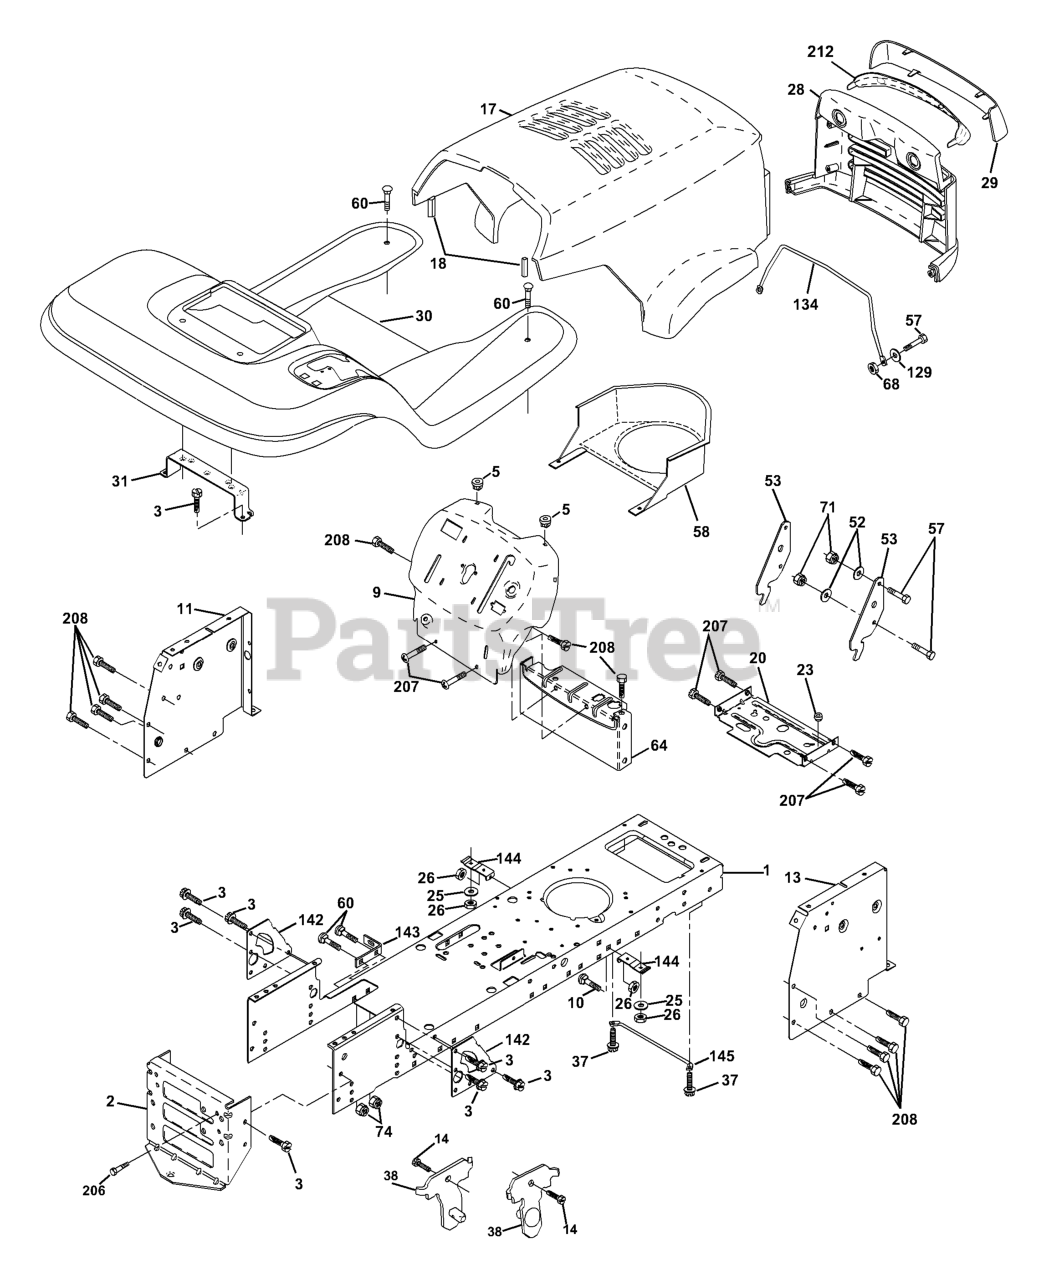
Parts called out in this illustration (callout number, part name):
1	CHASSIS STAMPING
2	DRAWBAR, 12GA
3	SCREW 3/8-16X3/4
5	BUMPER.RUBBER.HOOD
10	BOLT D
11	PANEL DASH LH
13	DASH PANEL ASM.
14	SCREW LT
17	HOOD
18	BUMPER HOOD T
20	PLATE MTG
23	BUSHING.SNAP.NYL.BLK.
25	WASHER
26	NUT
28	GRILL
29	LENS
30	FENDER, FOOTREST
31	BRACKET.SUPPORT.FENDER
37	Screw Thdrol 5/16-18 x 1/2 TYT
38	BRACKET.ASM.PIVOT.MOWER.REAR
52	WASHER
53	BRACKET PNT PICK OFF LT/PL
57	BOLT
58	AIR DUCT P/L/LT
60	Bolt Rdhd Sqnk 3/8-16unc x 3/4
64	DASH LOWER
68	NUT
71	NUT.CROWNLOCK.1/4
129	WASHER
134	ROD SUPPORT HOOD LT/PL HUS.
142	PLATE
143	BRACKET, SWAY BAR
144	BRKT, FOOT REST
145	ROD PIVOT CHASSIS/HOOD
206	SHOULDER BOLT 5/16-18TT
207	SCREW, 5/16-18 X 1/2
208	SCREW 3/8-16X1/2
212	INSERT LENS REFLECTOR
